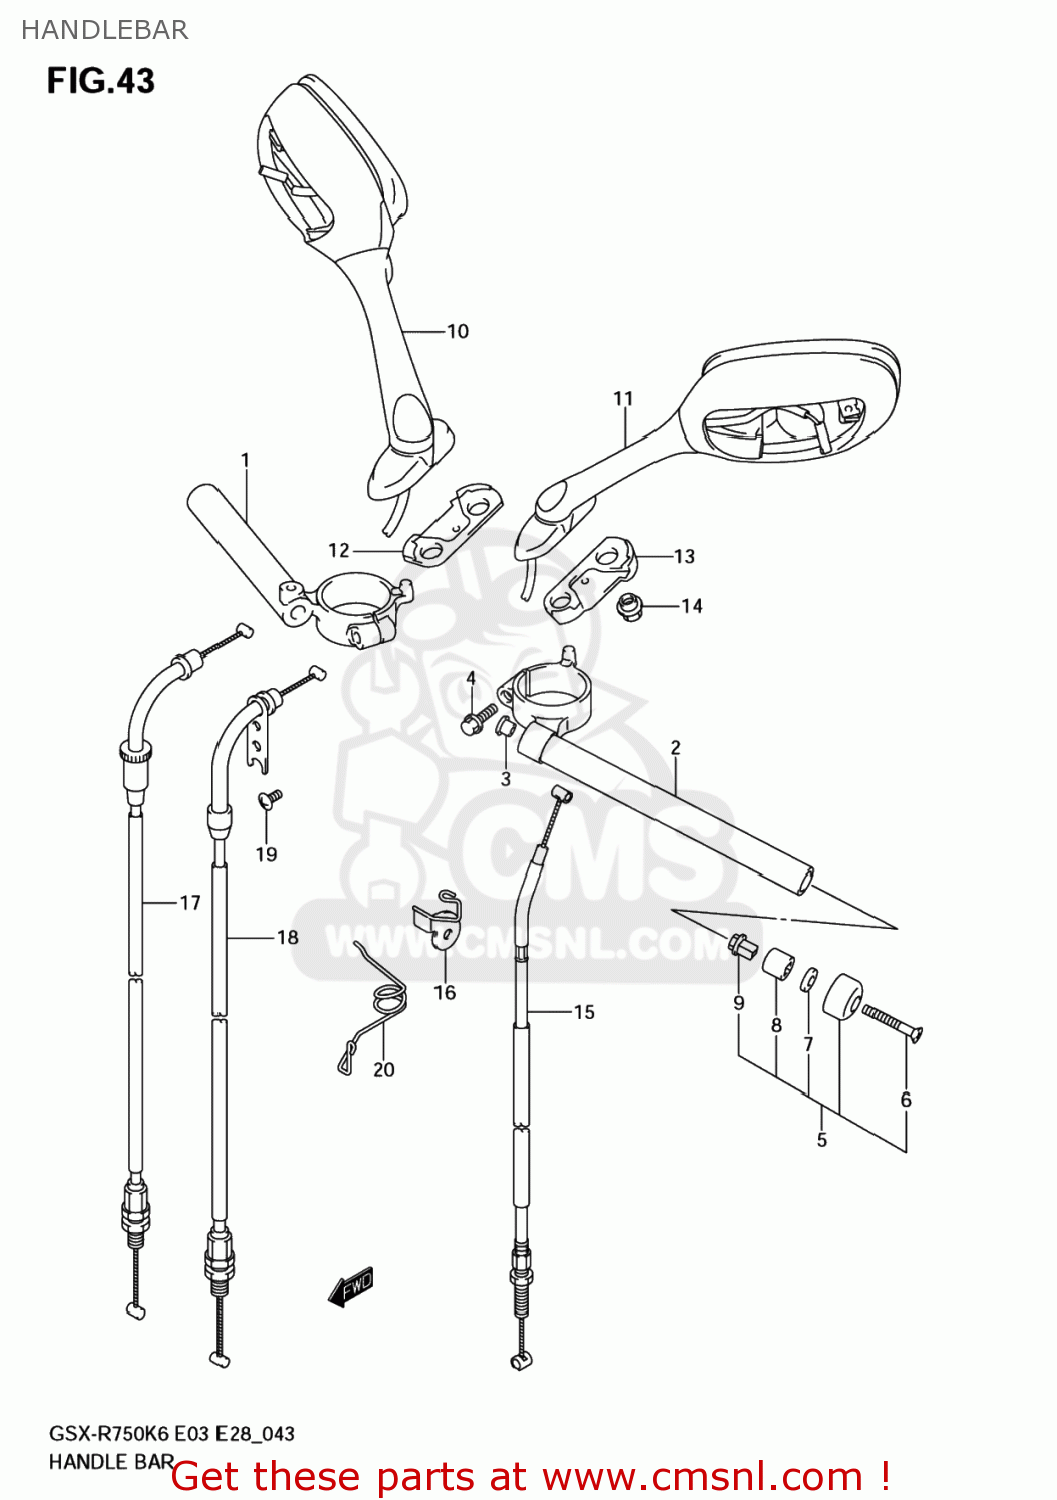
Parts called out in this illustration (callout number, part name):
1	HANDLEBAR,R
2	HANDLEBAR,L
3	CAP,HANDLEBAR
4	BOLT,HANDLEBAR
5	BALANCER SET,H
6	SCREW
7	WASHER(6.5X16X4)
8	EXPANDER,HANDLE BALANCER
9	NUT,HANDLE BAL
10	MIRROR ASSY,RE
11	MIRROR ASSY,RE
12	CUSHION,RR VIEW MIRRROR,R
13	CUSHION,RR VIEW MIRRROR,L
14	NUT,REAR VIEW
15	CABLE ASSY,CLUTCH
16	GUIDE,CLUTCH CABLE
17	CABLE ASSY,THROTTLE NO.1
18	CABLE ASSY,THROTTLE
19	SCREW
20	GUIDE,THROTTLE CABLE
